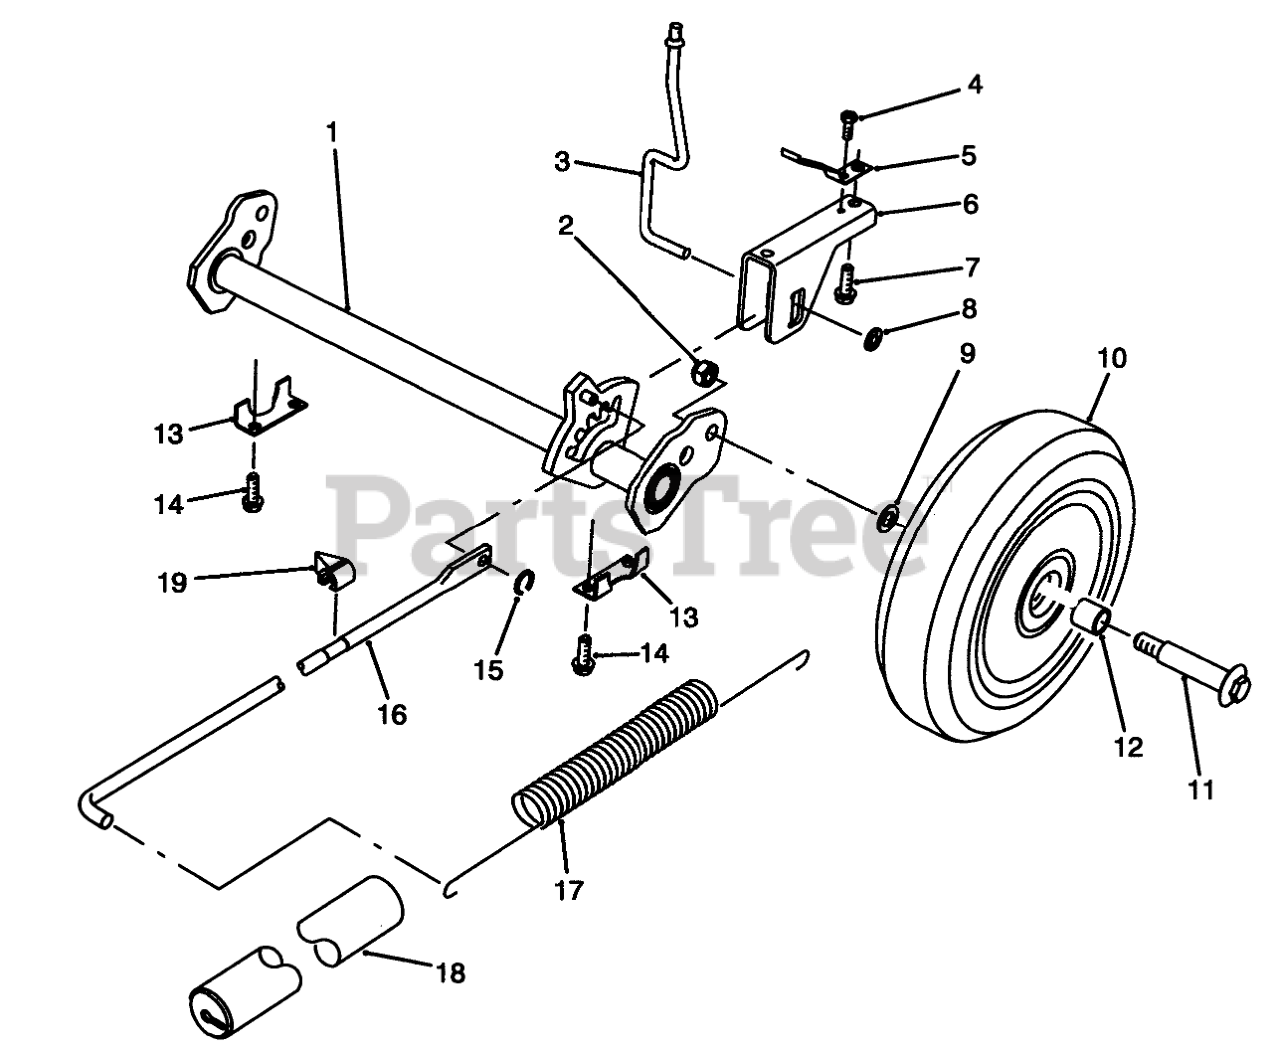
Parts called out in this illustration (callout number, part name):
1	PIVOT ARM REAR WA
2	NUT-HEX
3	TRIGGER ROD
4	SCREW 8 - 32 X 250
5	SPRING - TRIGGER RET
6	SADDLE - HOC
7	SCREW
8	PUSHNUT
9	WASHER
10	Wheel & Tire Assembly (Incl. Ref. #12)
11	BOLT-WHEEL
12	BUSHING
13	REAR SECURING PLATE
14	SCREW-HWH
15	GRIP RING
16	LINK ROD
17	SPRING-COUNTERBALANCE
18	COVER-SPRING
19	INDICATOR-HEIGHT OF CUT
